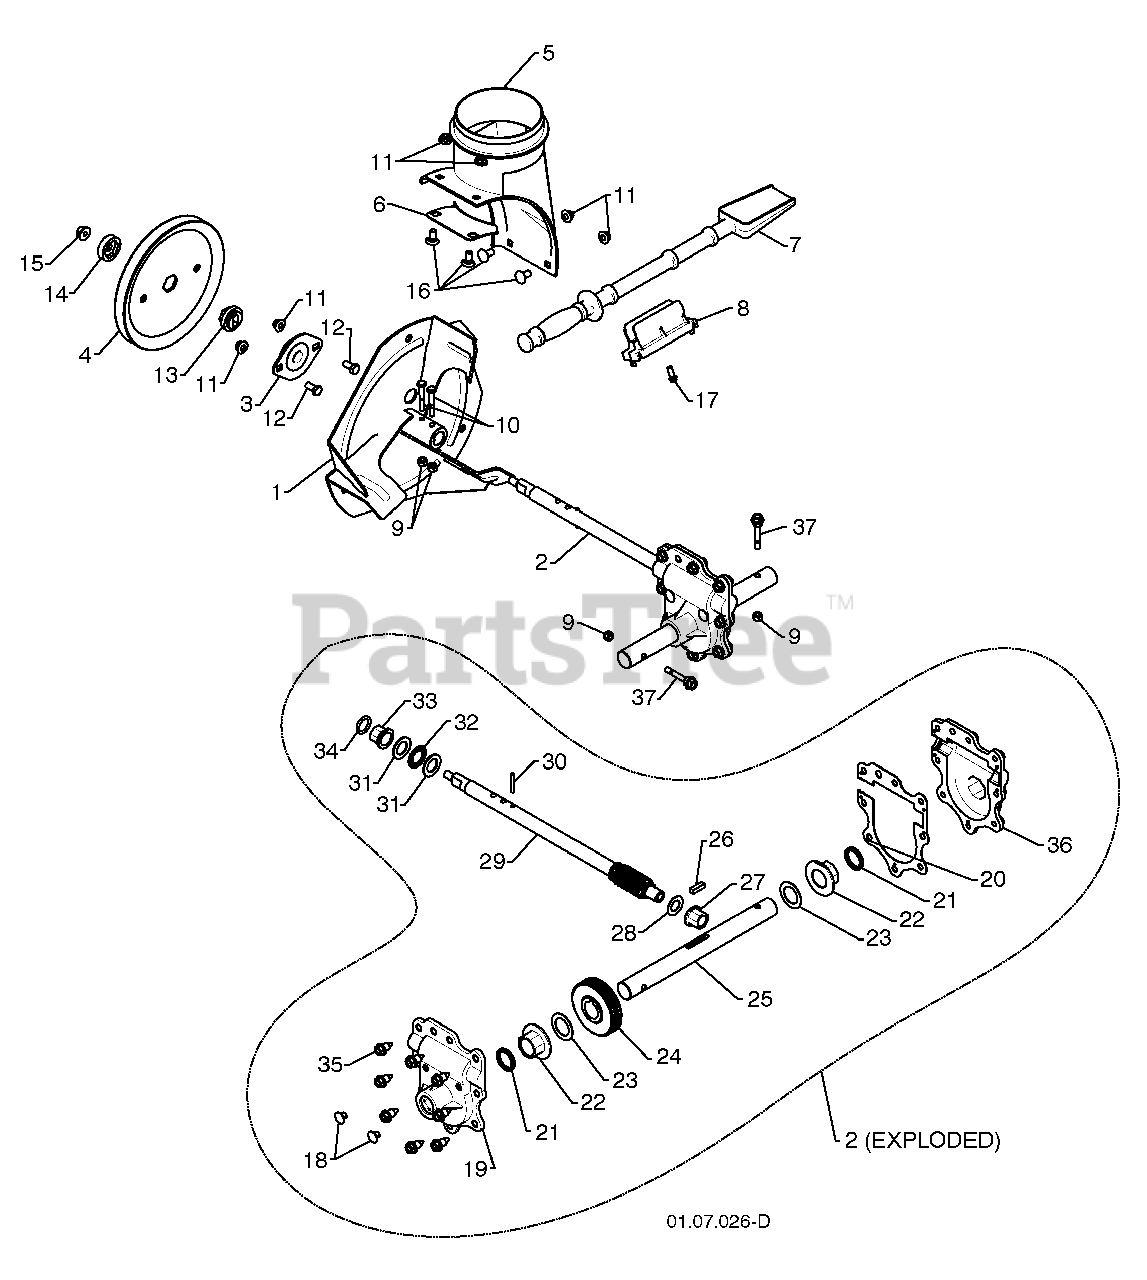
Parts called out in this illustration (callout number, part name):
2	GEARBOX ASSEMBLY
4	IMPELLER PULLEY
5	DISCHARGE BASE GRAY
6	CORNER BRACKET GRAY
7	CLEAN OUT TOOL
9	NUT 1/4-20
10	SCREW 1/4-20 X .625
11	NUT 5/16-18
12	SCREW 5/16-18 X .625
13	IMPELLER HUB
14	IMPELLER SLEEVE
15	NUT 3/8-16
16	CARRIAGE BOLT
17	SCREW 13-16 X .625
18	PLUG
19	GEARBOX COVER RH
21	SEAL
22	BEARING
23	THRUST WASHER 1.00
24	WORM GEAR
25	AUGER SHAFT
26	SQUARE KEY
27	BEARING
28	THRUST WASHER
29	IMPELLER SHAFT
30	ROLL PIN
31	THRUST WASHER
32	THRUST BEARING
35	SCREW 5/16-18 X .750
36	GEARBOX COVER LH
37	SHEAR BOLT
